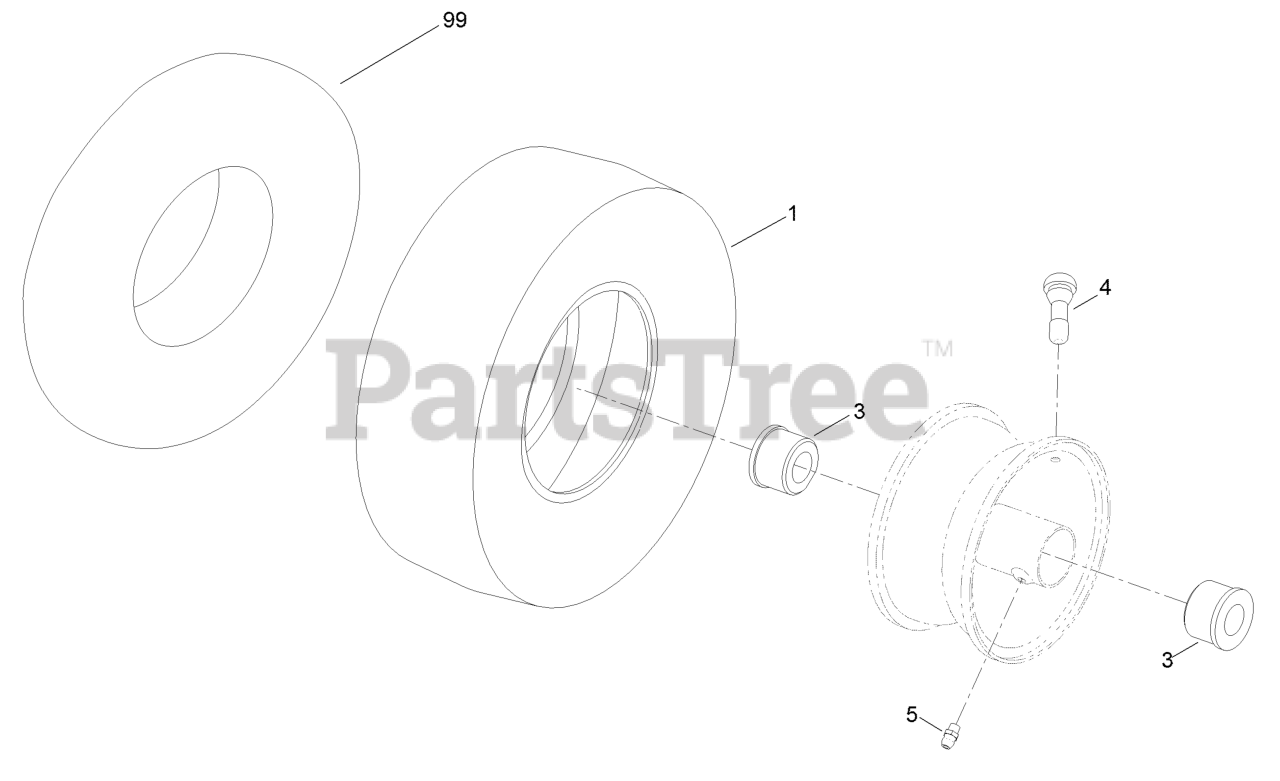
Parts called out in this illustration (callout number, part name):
3	BUSHING-FLANGE
4	Stem-Valve
5	FITTING-GREASE
99	TUBE-INNER
